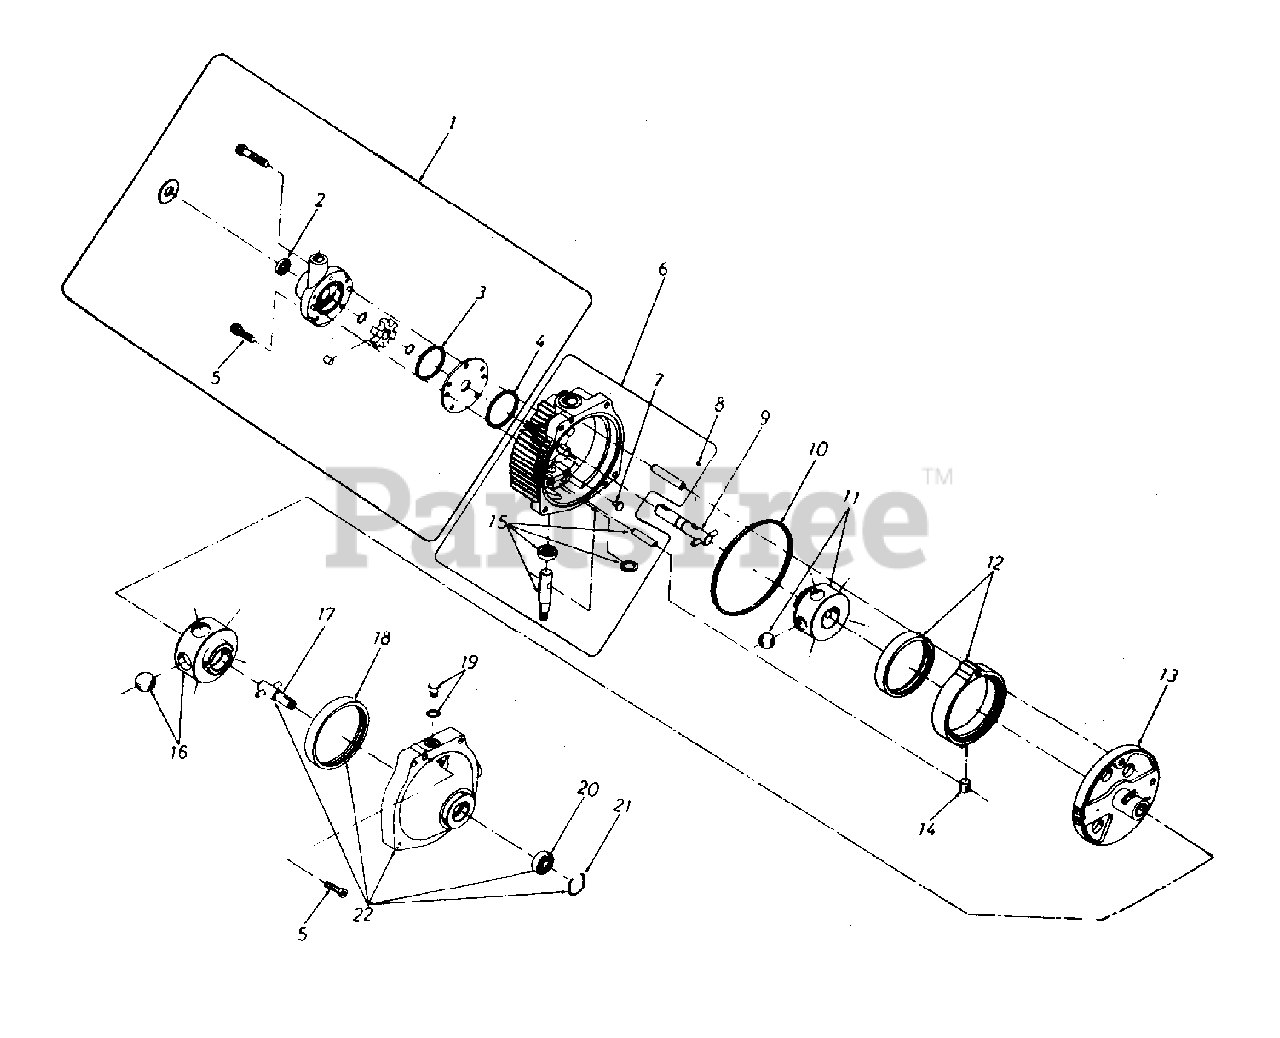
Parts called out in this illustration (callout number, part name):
1	Charge Pump Kit
2	Oil Seal
3	Square Cut Seal Ring .036
4	Square Cut Seal Ring .038
5	Socket Head Cap Screw 5/16-18 x 1.25" Long
6	Cover Subassembly
8	Drive Pin
9	Input Shaft Subassembly
10	Square Cut Seal Ring .166
11	Pump Rotor-Subassembly
12	Cam Ring Subassembly
13	Pintle Subassembly
14	Cam Ring Insert
15	Control Shaft Kit
16	Motor Rotor-Ball Subassembly
17	Output Shaft Subassembly
18	Motor Race
19	"O"-Ring Plug Subassembly
20	Ball Bearing (Output)
21	Retaining Ring
22	Body Subassembly
